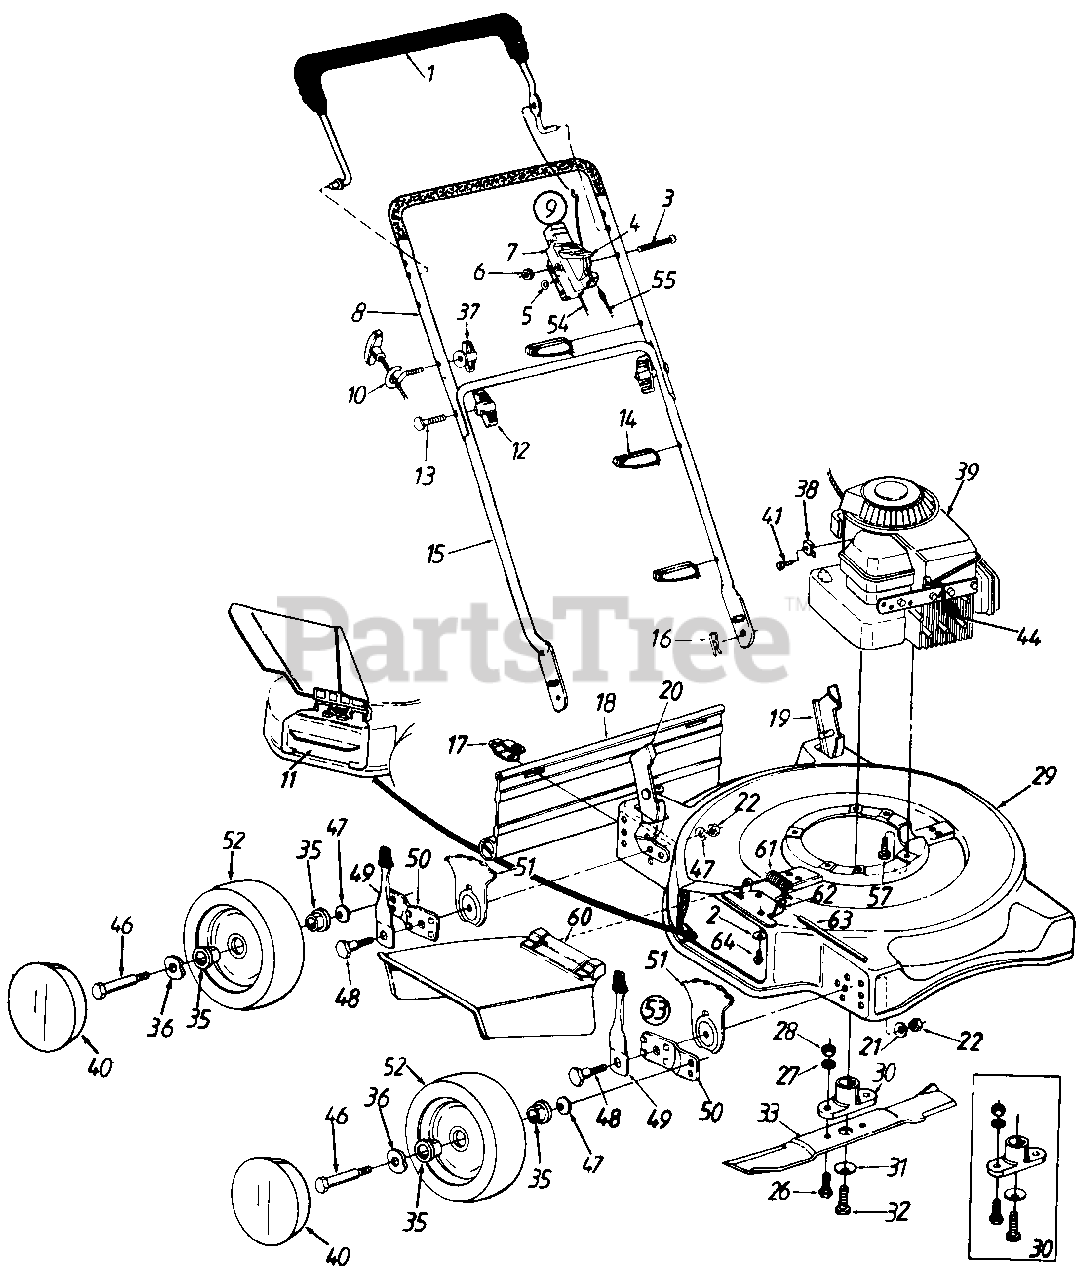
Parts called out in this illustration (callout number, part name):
1	Control Handle Ass'y.
2	Bell-Wash. 1/4" I.D.
3	Oval C-Sunk Mach. Scr.
4	Throttle Lever
5	Spr. Wash. .66" I.D.
6	Hex L-Nut 1/4-20 Thd.
7	Throttle Body
10	Rope Guide
11	Mulching Plug
12	Hand Knob
13	Curved Hd. Bolt 5/16-18 x 2" Lg.
14	Cable Tie
16	Hairpin Cotter
17	Hinge Clip
18	Rear Flap
19	Handle Bracket Ass'y.-L.H.
20	Handle Bracket Ass'y.-R.H.
21	Bell-Wash. .39" I.D. x 1.38"
22	Hex Nut 3/8-16 Thd.
26	Hex Bolt 3/8-24 x 1" Lg.
27	L-Wash. 3/8" I.D.
28	Hex Nut 3/8-24 Thd.
31	Bell-Wash. .39" I.D.
32	Hex Bolt 3/8-24 x 1.5" Lg.
33	20" Blade
35	Ball Bearings
36	Wave Washer
37	Wing Nut 1/4-20 Thd.
38	Cable Clamp
39	Engine
40	Hub Cap (Beige)
41	Hex Wash. Hd. Tap Scr. #10-32 x.62" Lg.
44	Spark Plug Boot
46	Axle Bolt
47	Bell-Wash. .400" I.D. x .88"
48	Shld. Bolt .50" Dia. x .357"
49	Spring Lever Ass'y. w/Knob
51	Height Adj. Plate
52	Wheel Ass'y. Comp. (Beige)
53	Height Adj. Ass'y. Comp.- R.F. & L.R.
54	Throttle Cable-51"
55	Control Cable-39"
57	Hex L-Wash. Hd. Scr. 3/8-16 x 1.0" Lg.
60	Chute Deflector Ass'y.
61	Torsion Spring
62	Adapter Plate
63	Hinge Pin
64	Hex Self-Tap Scr. 1/4-20 x .5"
